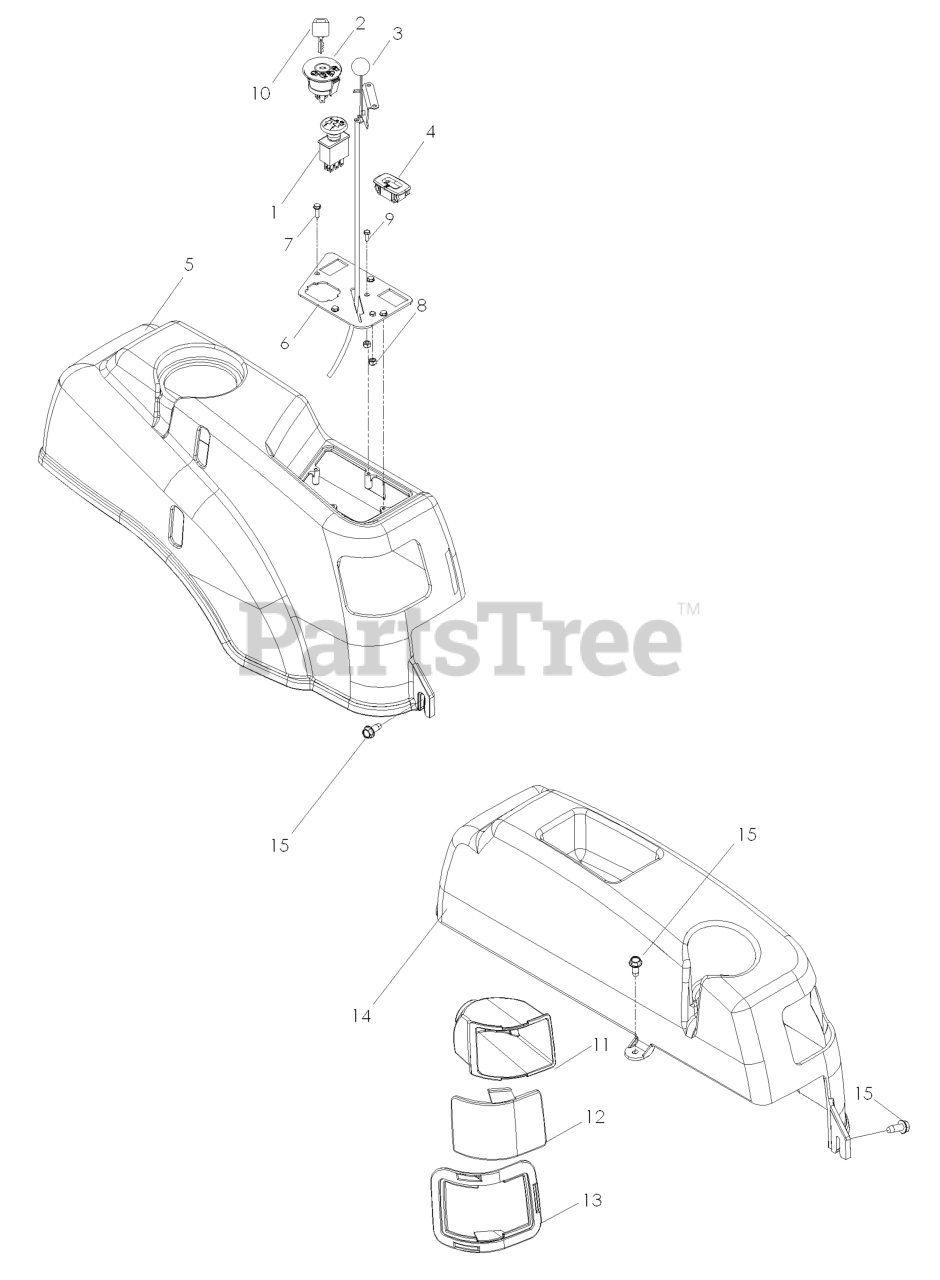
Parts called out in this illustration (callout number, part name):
1	RP.SWITCH, BLADE
2	RP IGNITION SWITCH
3	THROTTLE CABLE DETENT
4	HOUR METER
5	RP.FENDER, RT
6	PLATE.CONTROL.CONSOLE.BLACK
7	SCR #10-12X3/4 HEX WAS HD ZD
8	NUT 10-24 NYLOC
9	HCS #10-24 X 1/2
10	KEY
11	LEFT HEADLIGHT REFLECTOR
11	RT HEADLIGHT REFLECTOR
12	LENS, COLORED LEFT
12	LENS, COLORED RIGHT
13	RT HEADLIGHT RIM GREY
13	LEFT HEADLIGHT RIM GREY
14	FENDER, LT
15	SCREW 1/4 X 5/8
